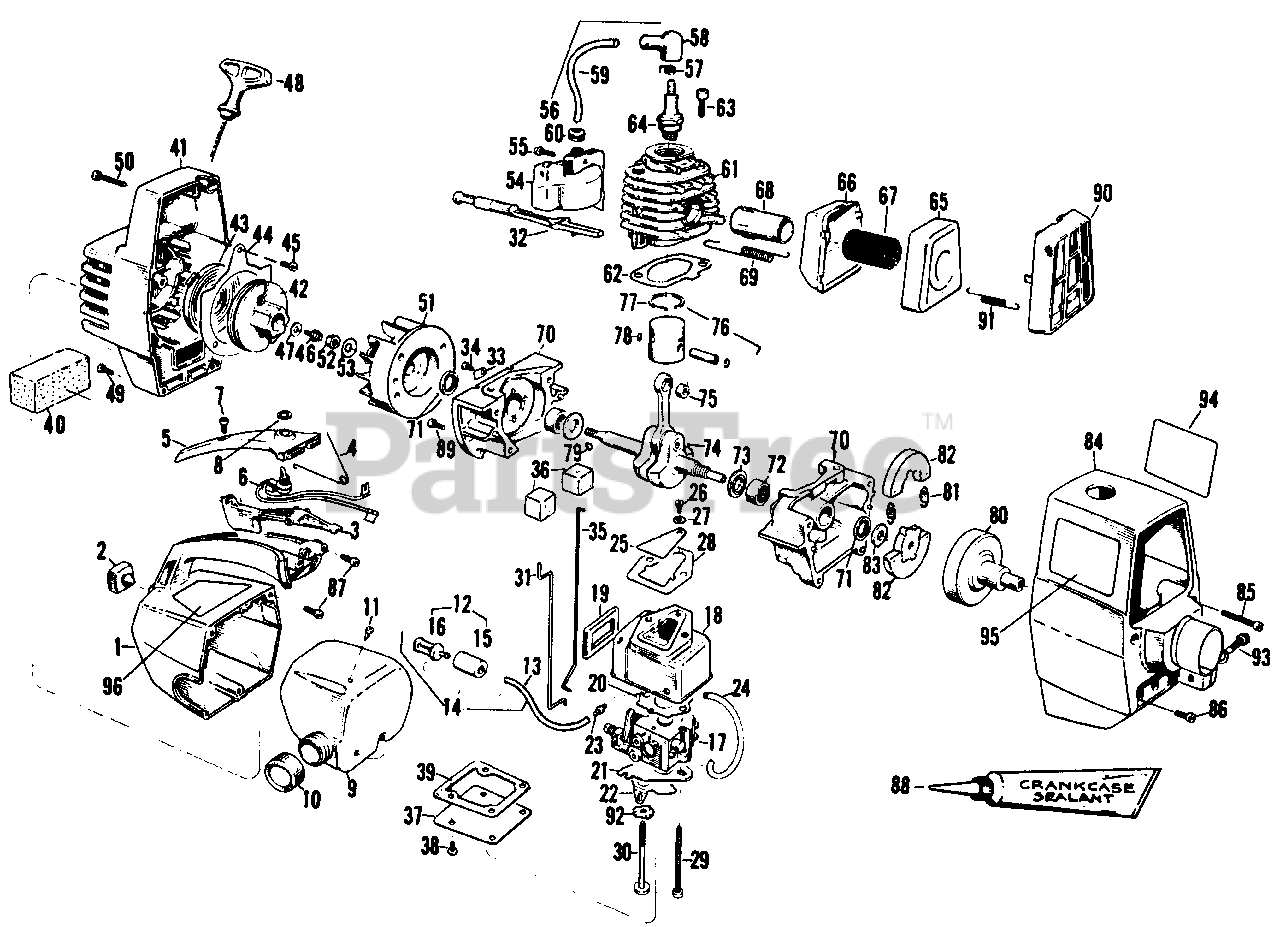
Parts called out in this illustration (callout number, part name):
1	Handle & Fuel Tank Housing
2	Bumper-Fuel Tank Housing
3	Trigger-Throttle
4	Trigger Spring
5	Handle Cover
6	Grounding Switch
7	Screw-Handle Cover
8	Nut-Grounding Switch
9	Fuel Tank (Includes 11 & 13)
10	Fuel Cap
11	Duck Bill Valve
12	Fuel Line Assy. (Includes 14 & 15)
13	Fuel Line
14	Fuel Line Pickup Assy. (Includes 16 & 17)
15	Fuel Filter
16	Fuel Filter Weight
17	Carburetor
18	Carburetor Housing
19	Seal Carburetor Case
20	Carburetor Gasket
21	Choke Wire Guide Plate
22	Choke Shutter
23	Fuel Line Fitting
24	Fuel Line Carburetor
25	Reed Valve
26	Screw-Reed Valve
27	Washer-Reed Valve Screw
28	Gasket-Carb. Housing to C'case
29	Screw Carburetor
30	Screw-Carburetor Shoulder
31	Choke Wire
32	Choke Knob
33	Clamp-Choke Wire
34	Screw-Choke Wire Clamp
35	Throttle Wire
36	Throttle-Choke Wire Boots
37	Cover-Carburetor Case
38	Screw-Carburetor Case Cover
39	Gasket-Carburetor Case Cover
40	Air Filter
41	Fan Housing
42	Starter Pulley
43	Starter Recoil Spring
44	Air Baffle
45	Screw Air Baffle
46	Screw-Pulley
47	Washer-Starter Pulley Screw
48	Rope and Handle-Starter
49	Screw-Fan Housing Bottom
50	Screw-Fan Housing Top
51	Flywheel Assy
52	Nut-Flywheel
53	Washer-Flywheel
54	Module-Ignition
55	Screw-Ignition Module
56	High Tension Lead Assy. (Includes 58,59 & 60)
57	Connector-Spark Plug Lead
58	Boot-Spark Plug
59	High Tension Lead Wire
60	Grommet-Plug Wire
61	Cylinder
62	Gasket-Cylinder
63	Screw-Cylinder
64	Spark Plug (Champion RC-J8)
65	Cover Muffler
66	Body Muffler
67	Screen-Spark Arresting
68	Diffuser-Muffler
69	Spring-Muffler Attachment
70	Crankcase Assy. (Includes 72 & 73)
71	Seal-Crankshaft
72	Bearing-Crankshaft
73	Washer-Crankshaft Thrust
74	Crankshaft & Rod Assy
75	Bearing-Wrist Pin
76	Piston Assy. (Includes 78 & 79)
77	Piston Ring
78	Retainer-Wrist Pin
79	Key-Flywheel
80	Drum Coupling & Bearing Assy
81	Spring-Clutch
82	Clutch Assembly (Includes 82)
83	Washer-Inner
85	Screw-Shroud Top
86	Screw-Shroud Bottom
87	Screw-Fan Housing to handle & Fuel Tank
88	Crankcase-Sealant 3 oz. Tube
89	Screw-Crankcase
90	Guard-Muffler
91	Spring-Muffler Guard
92	Washer-Wave
93	Bolt-1/4-20 x 1" (Hex)
94	Decal-Shroud (left)
95	Decal-Shroud (right)
96	Decal-Starting Instruction
